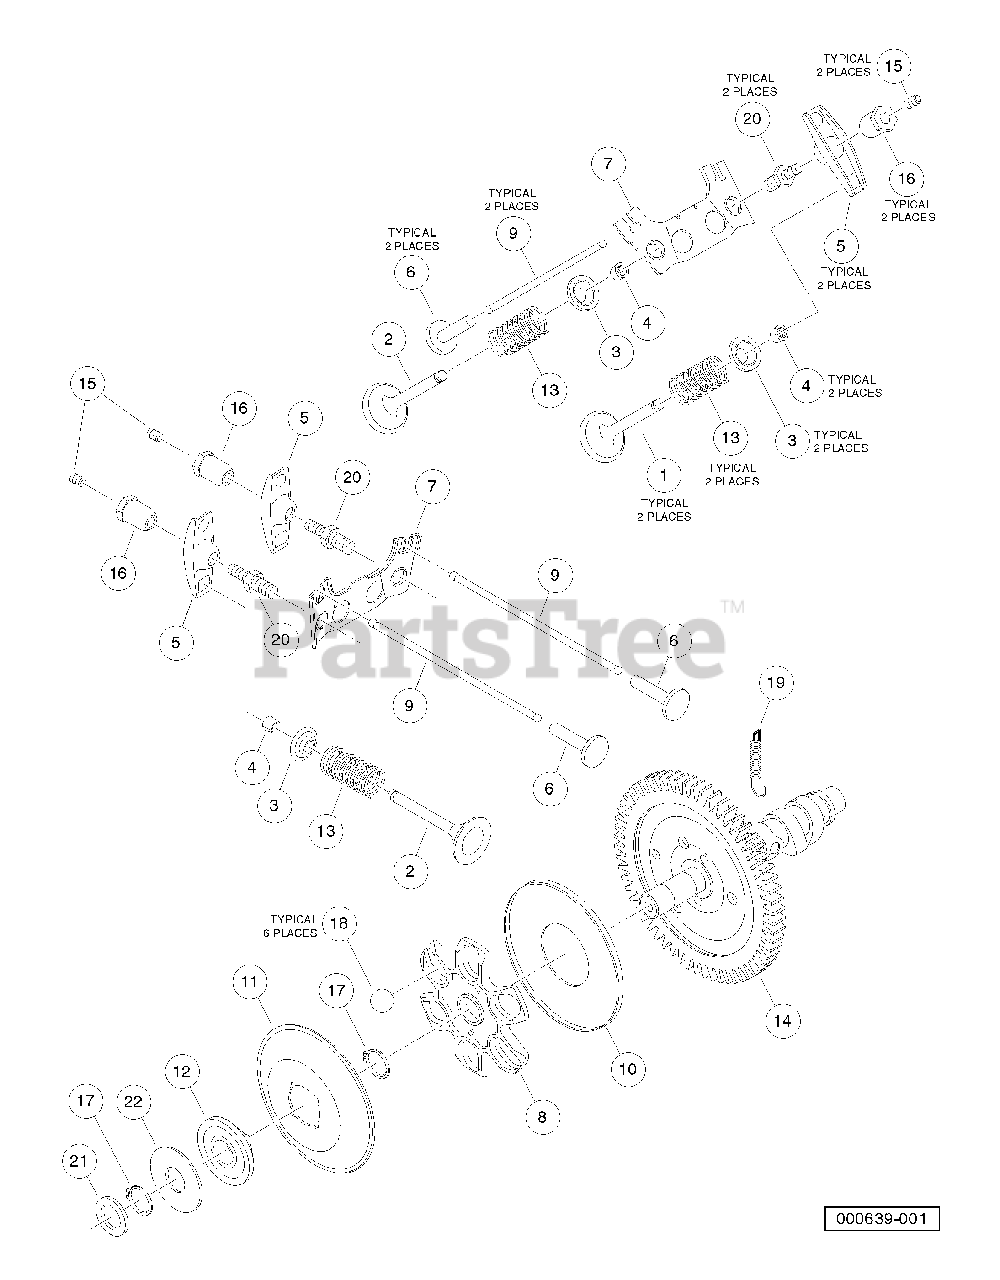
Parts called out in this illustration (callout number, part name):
1	Va Ivg , Inta kg , Fh
2	Valve, Exhaust, Fh
3	Retainer, Valve Spring, Fh
4	Collet, Spring, Valve, Fh
5	Arm, Rocker
6	Tappet, Rod, Push, Fh
7	Guide, Arm, Rocker, Fh
8	Guide, Camshaft, Gov, Fh
9	Rod, Push, Fh
10	Plate, Camshaft, Gov, Fh
11	Plate, Ring, Gov, Fh
12	Sleeve, Plate, Gov, Fh
13	Spring, Valve, Fh
14	Kit, Camshaft, Comp, Fh
15	Screw, Rocker Arm, Fh
16	Nut, Arm, Rocker, Fh
17	Ring, Snap, Gov, Fh
18	Ball, Guide, Gov, Fh
19	Spring, Camshaft, Fh
20	Stud, Rocker Arm, Fh
21	Washer, Sleeve, Gov, Fh
22	Washer, Gov, Fh
